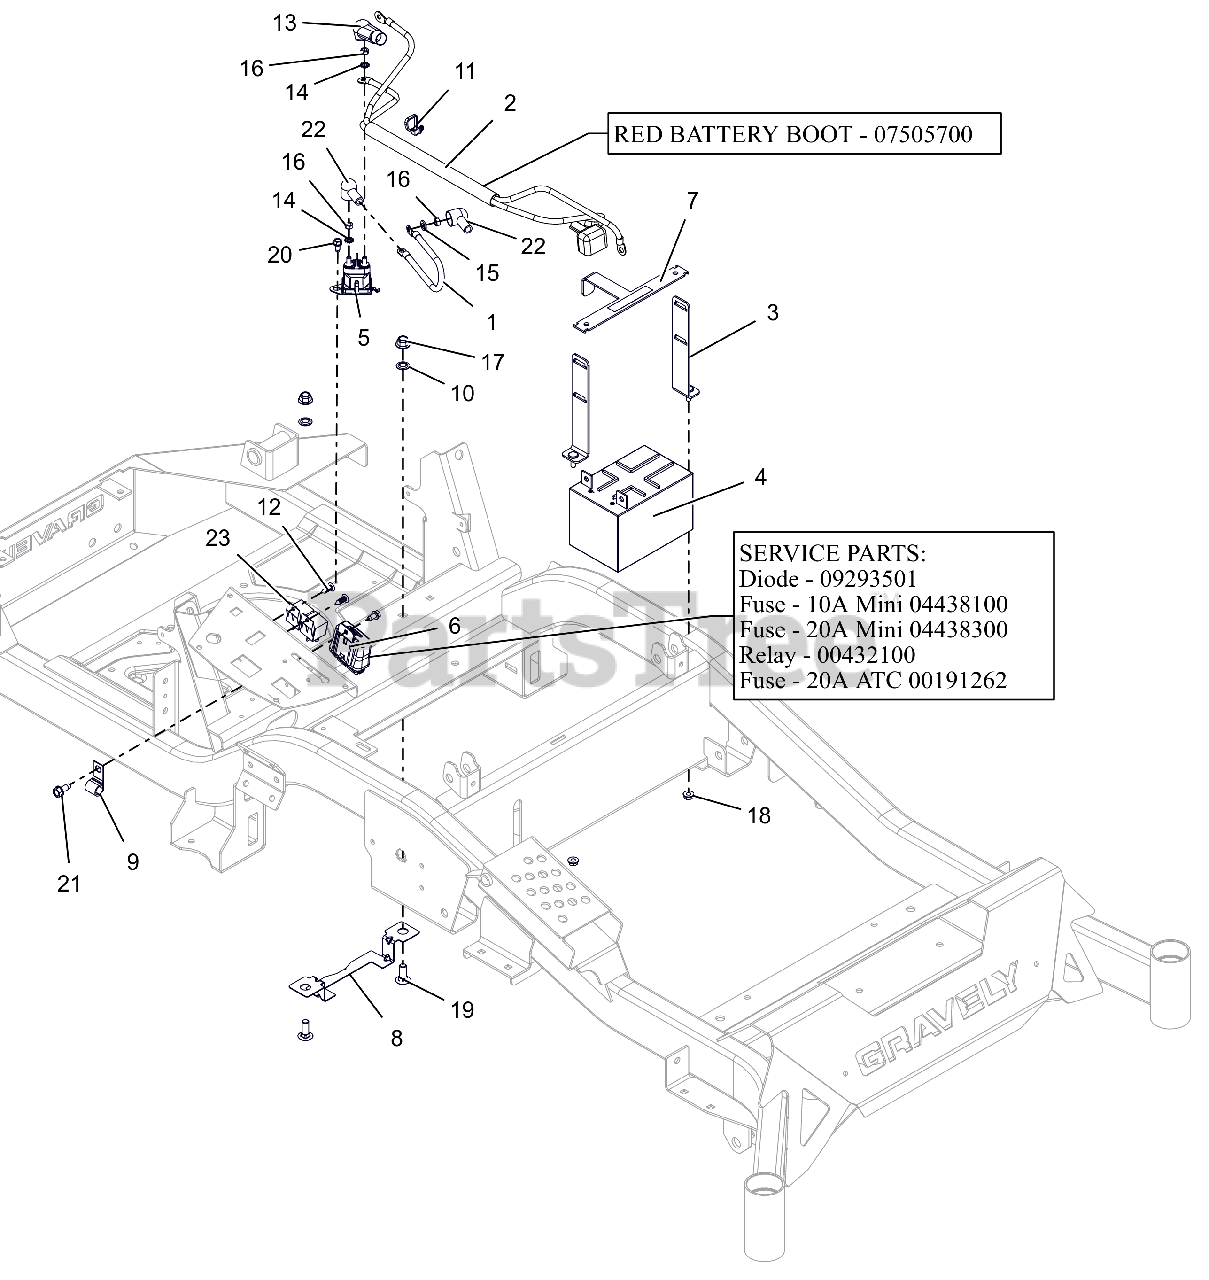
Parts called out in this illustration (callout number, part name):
1	CABLE, POS W/(2)1/4 RING 9.0LG
2	HARNESS, BATTERY HD
2	INSULATOR
3	WMT,BATTERY MOUNT HOLD DOWN
4	BATTERY, 12V 12A-190CCA
5	SOLENOID, STARTER (SEALED)
6	HARNESS, WIRE
6	DIODE, CONNECTOR SHELL
6	FUSE,10 AMP MINI-ATC
6	FUSE,20 AMP MINI ATC
6	RELAY,SEALED W/DIODE
6	FUSE, 20 AMP BLADE S/O
7	BRKT, BATTERY TIE DOWN
8	GUARD, ELECTRICAL HARNESS
10	NUT-PUSH .38 DIA. PAL ZINC
11	CABLE TIE W/ TREE (.25 HOLE)
12	RIVET, .25 NYLON PANEL
13	BOOT, .65ID POS
14	WSHR,LK-EXT.262X.502X.026 ZCC
15	WSHR,LK-REG .312X.078 ZCC
16	NUT-STD M6-1.0 ZCC
17	NUT,NYL-FLG .38-16 GF ZCC
18	NUT-LK-TOP-FLG .250-20 GF ZCC
19	BLT, RHSN .38-16X1.00 G5 ZCC
20	SCR-TAP .25-20X.50 HWH ZCC
21	SCR,TAP .312-18X.75 HWH TR ZCC
22	BOOT, EYELET TERMINAL
23	RELAY,SEALED W/DIODE
